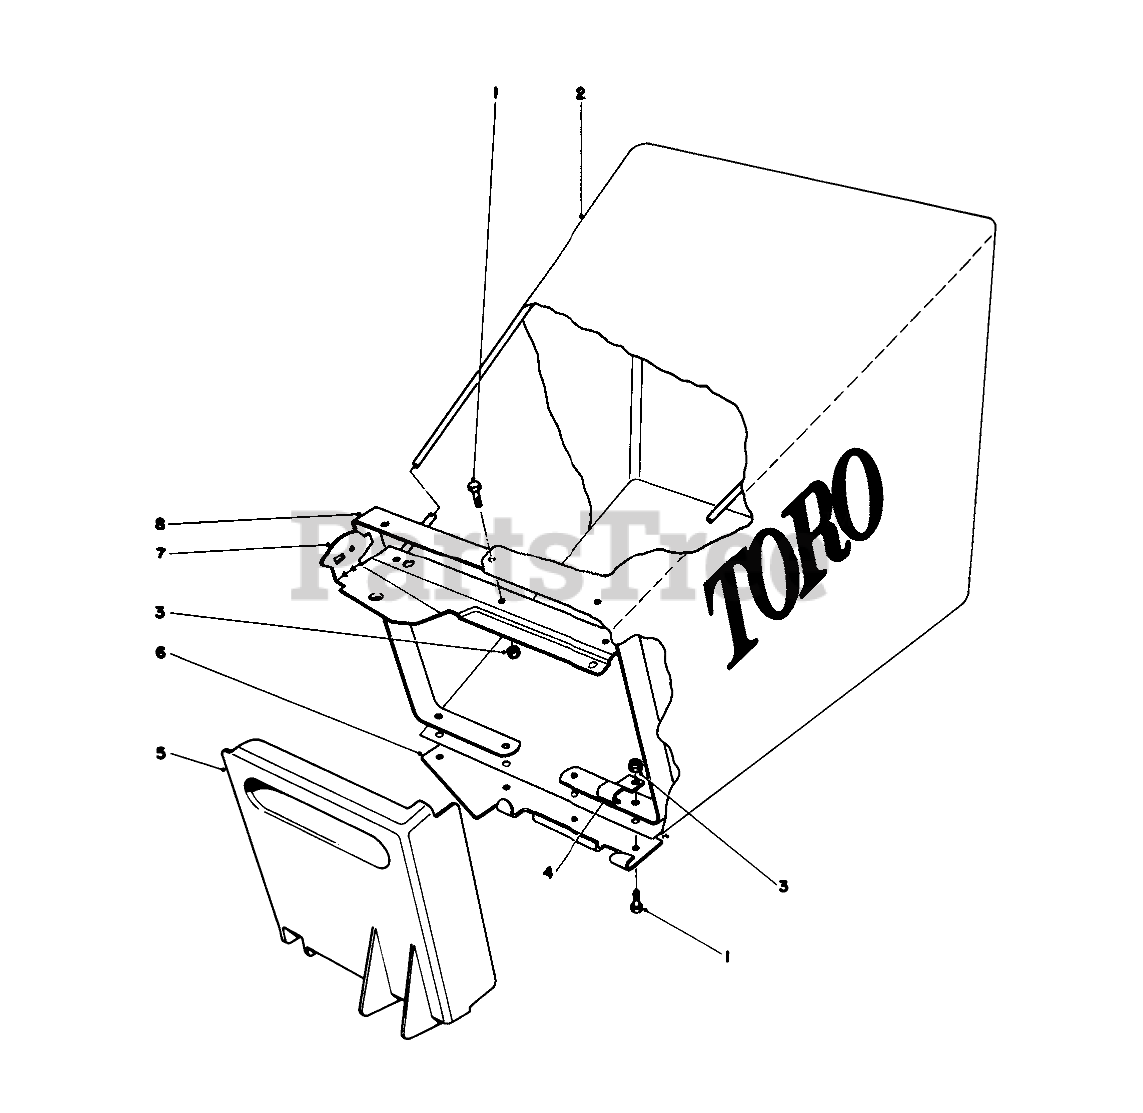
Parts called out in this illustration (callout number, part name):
1	SCREW-HWH
5	BAG DOOR
7	BAG FRAME ASM
8	LOWER BAG FRAME
